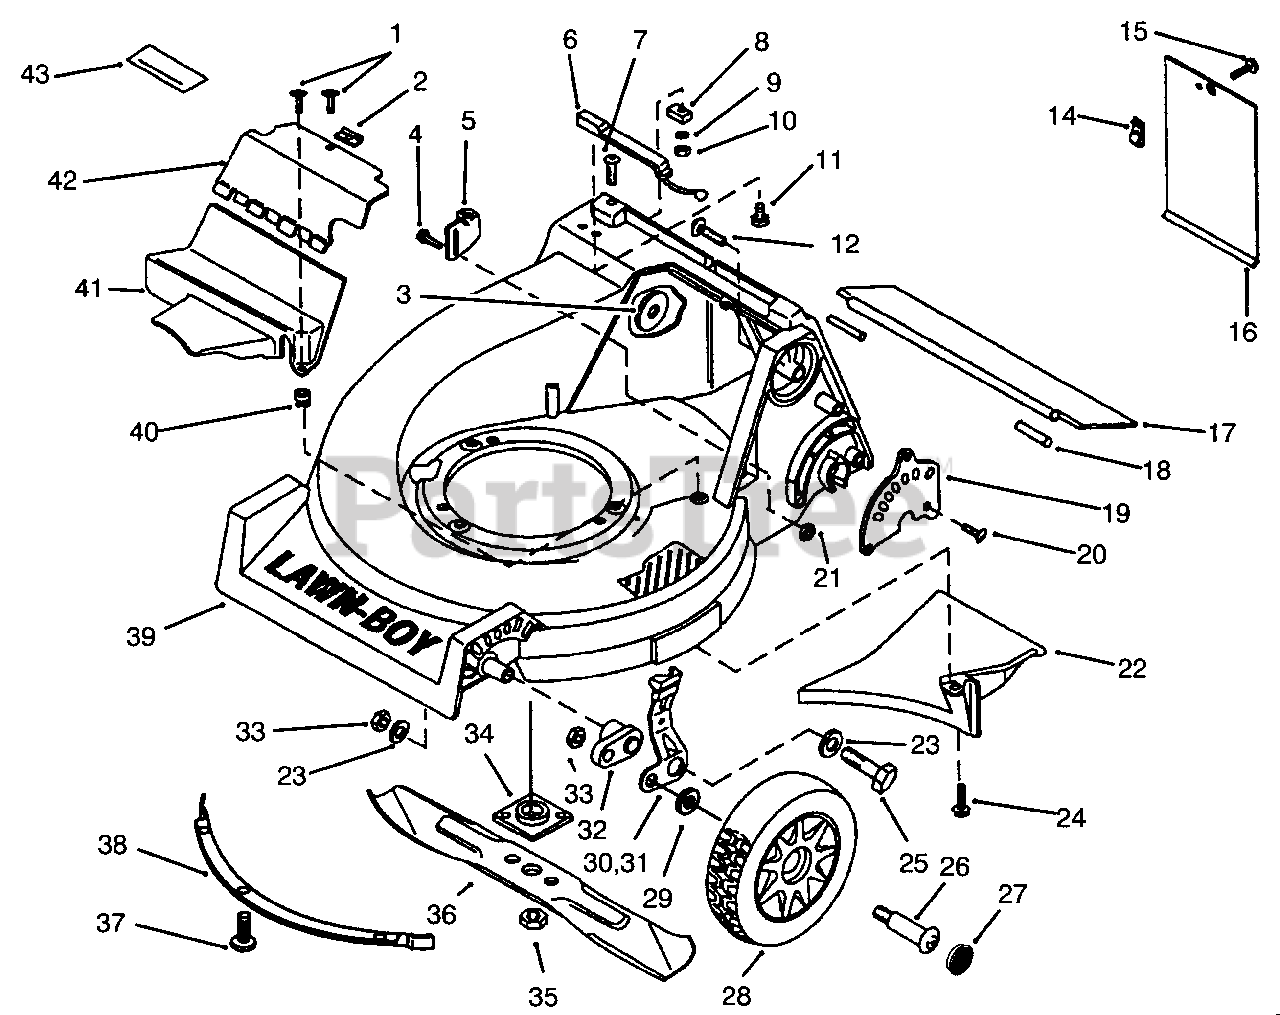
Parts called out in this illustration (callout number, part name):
2	Nut-Speed
3	Washer
5	Anchor-Cable
6	Arm-Switch
9	Washer-Lock
11	Screw-Stainless
12	Bolt-Ribbed Neck
14	Nut-Speed
16	Door-Access
17	Shield-Trailing
20	Screw-Button Head
21	Nut-Lock
22	Baffle-Chute
24	Screw-Hex Washer Hd.
26	Bolt-Shoulder
28	Wheel & Tire Assembly 8"
30	Knob & Spring
31	Knob & Spring
32	Arm-Height Adjustment
33	Nut-Lock
34	Plate & Collar
35	Nut-Blade
36	Blade-21"
37	Screw-Button Head
38	Baffle-Front
39	Housing-21"(Incl. Ref. #43)
40	Grommet
41	Cover-Drive Loose
42	Cover-Drive Upper
43	Decal-Danger
